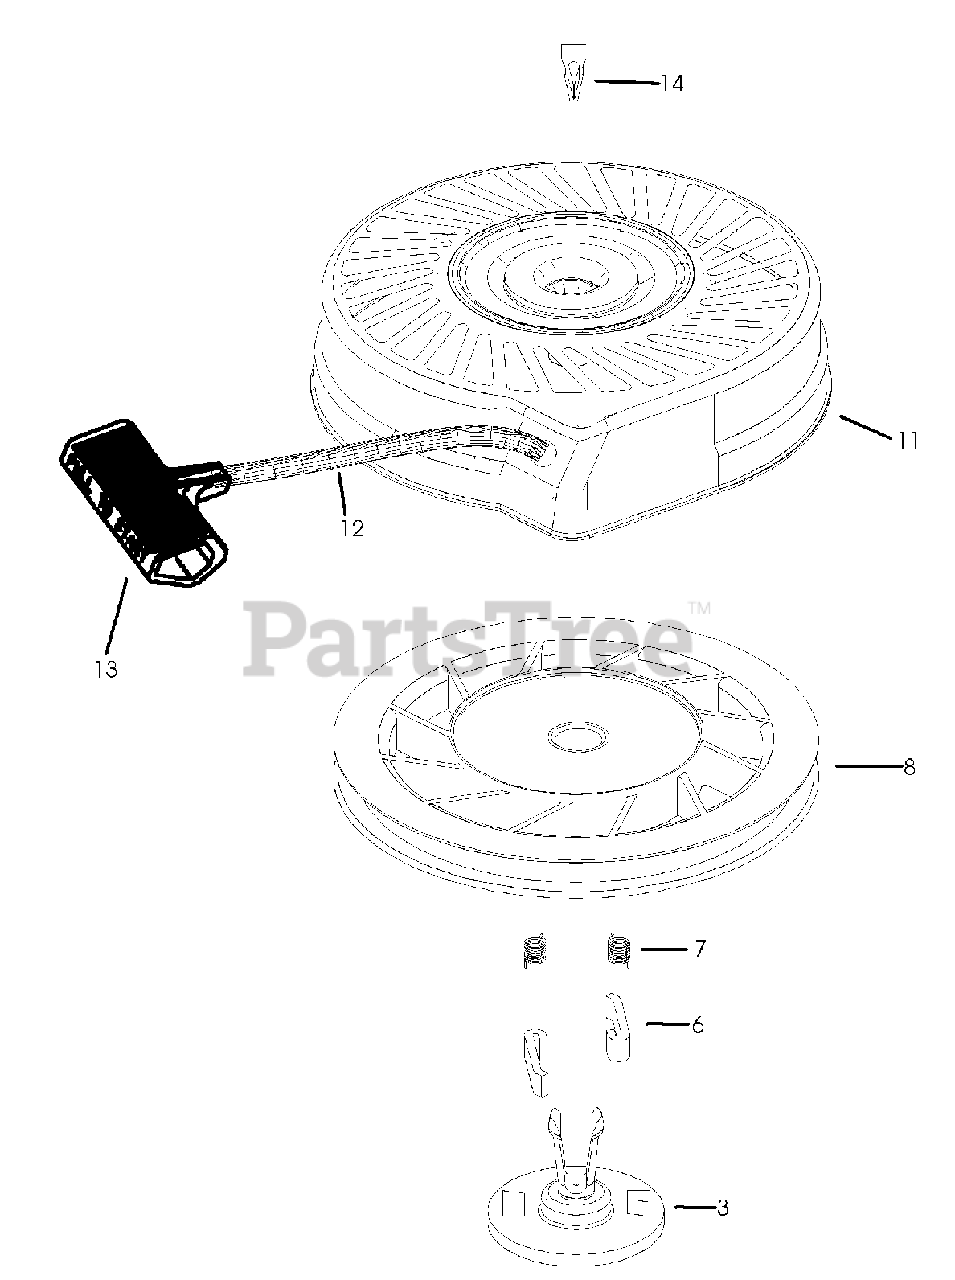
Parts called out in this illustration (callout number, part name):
3	Retainer
6	Dog-Starter
7	Dog Spring
8	Pulley & Rewind Spring ASM
11	Housing Assemble-Starter
12	Rope Starter
13	Handle-Starter
14	Cup Washer
